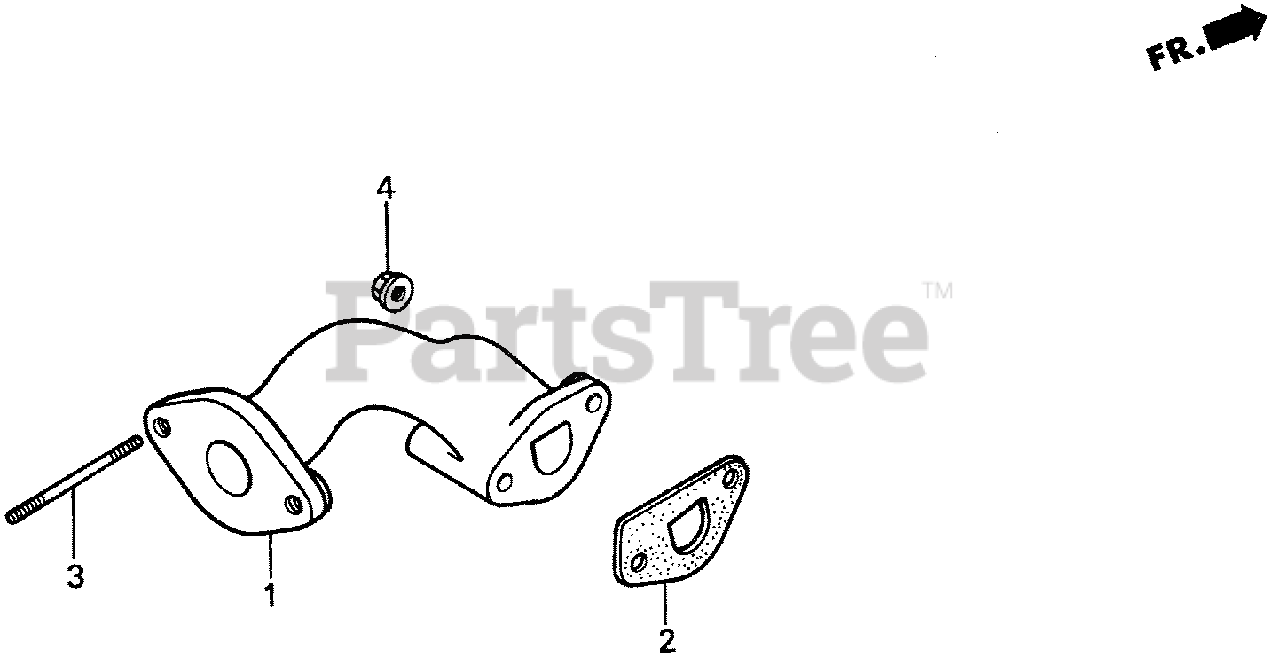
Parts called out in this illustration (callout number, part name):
2	GASKET, MUFFLER
3	BOLT, STUD (6X45)
4	NUT, FLANGE (6MM)
